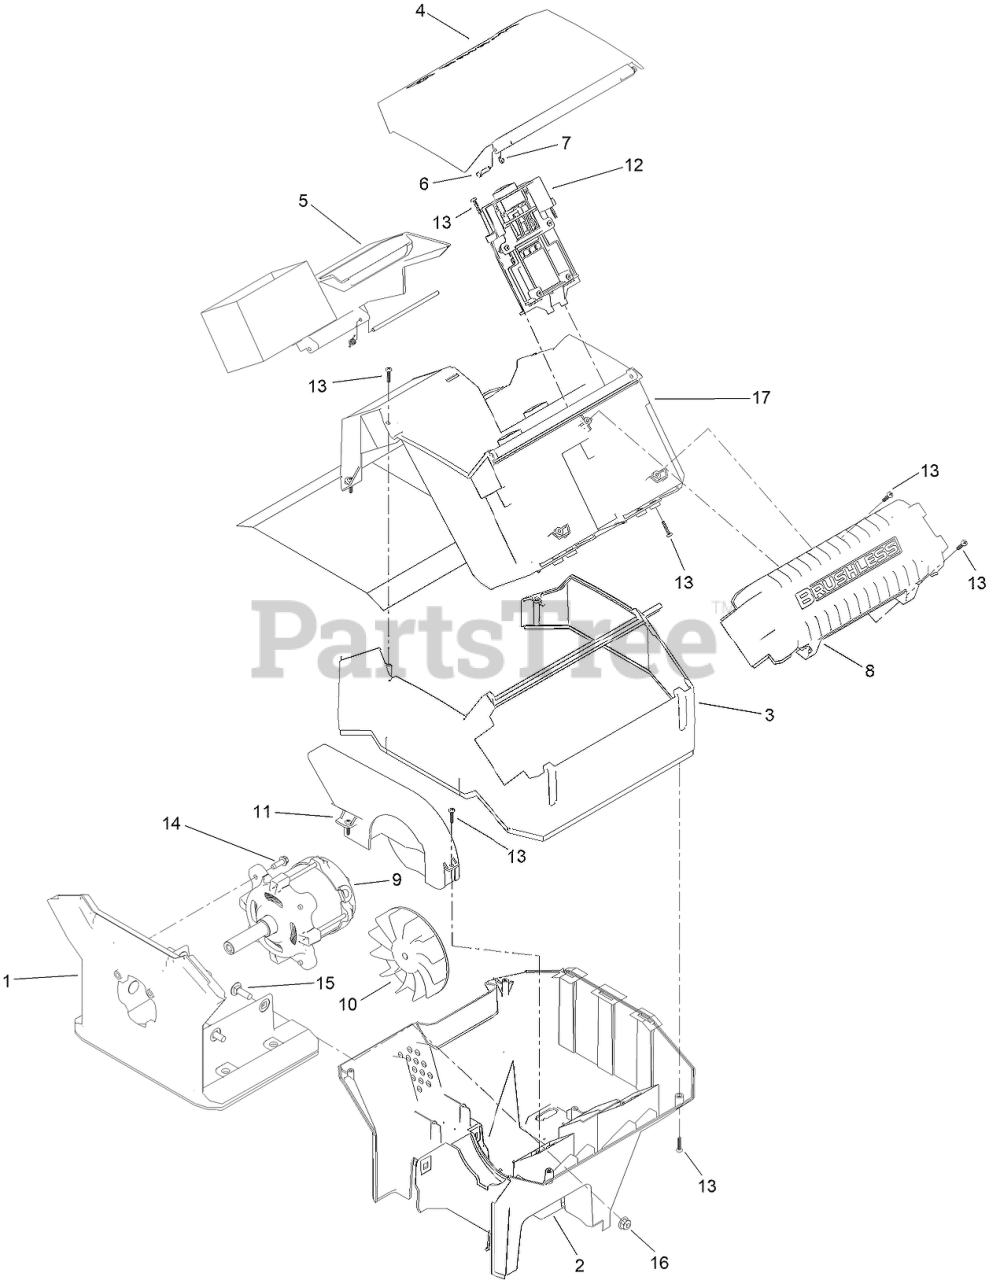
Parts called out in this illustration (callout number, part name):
1	MOTOR MOUNT
2	HOUSING-MOTOR
3	COVER-CONTROLLER
4	DOOR-TOP
5	DOOR-BOTTOM
6	PIN-THROTTLE CABLE
7	RING-RETAINING
8	HEATSINK
9	MOTOR-60V, 2 STAGE
10	FAN-FC
11	COVER-FAN
12	BATTERY TRACK ASSEMBLY
13	SCREW-PPH
14	SCREW-HWHTF
15	BOLT-CARR
16	NUT-HF, NI
17	BUCKET-BATTERY
